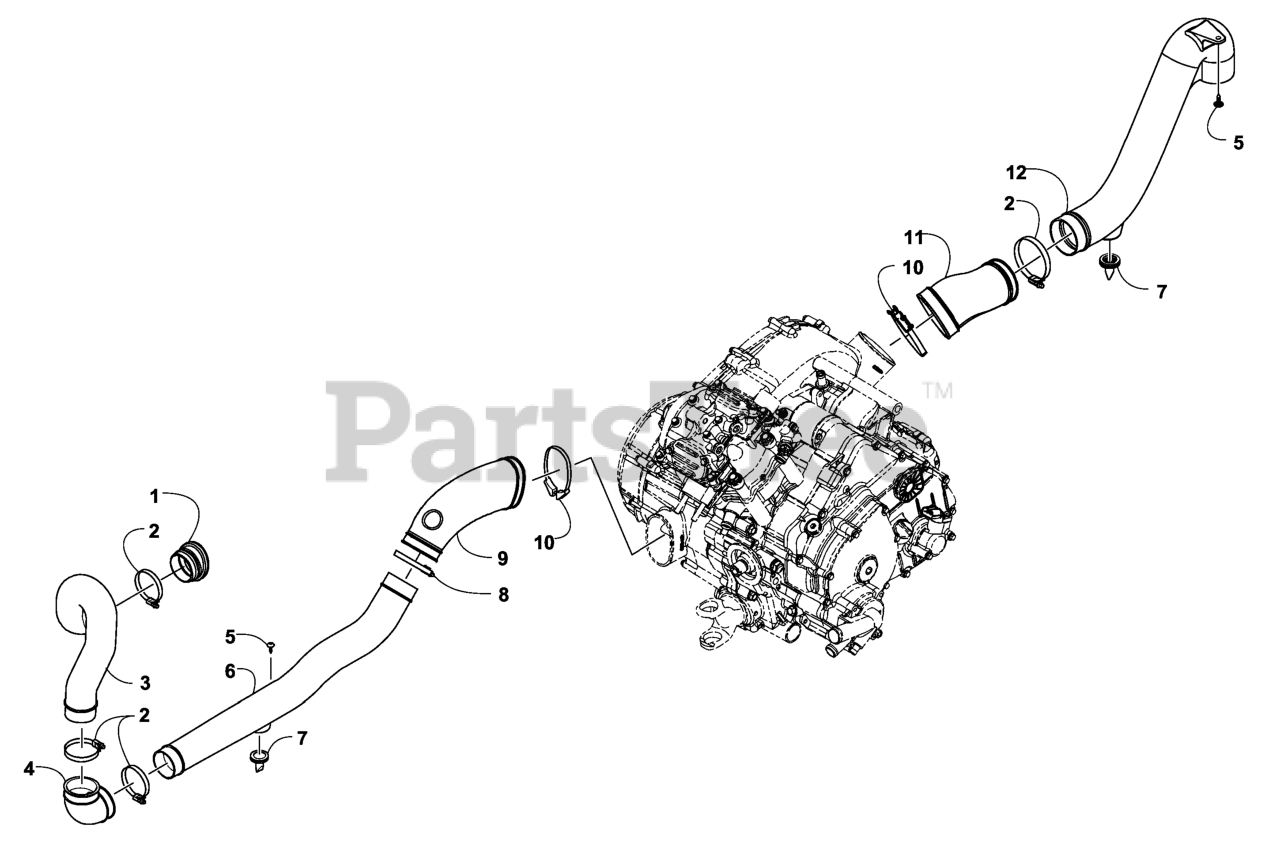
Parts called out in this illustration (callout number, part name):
1	GROMMET-CLUTCH INTAKE
2	CLAMP-WORM, HOSE
3	DUCT-CLUTCH, AIR IN
4	BOOT-AIR DUCT
5	SCREW-TSTRH, SELFTAP
6	DUCT-CLUTCH IN, #1
7	VALVE-AIR CLEANER
8	CLAMP-WORM, HOSE
9	BOOT-CLUTCH, IN
10	CLAMP-SCREW, OVAL
11	BOOT-DUCT, AIR OUT
12	DUCT-AIR, OUT
